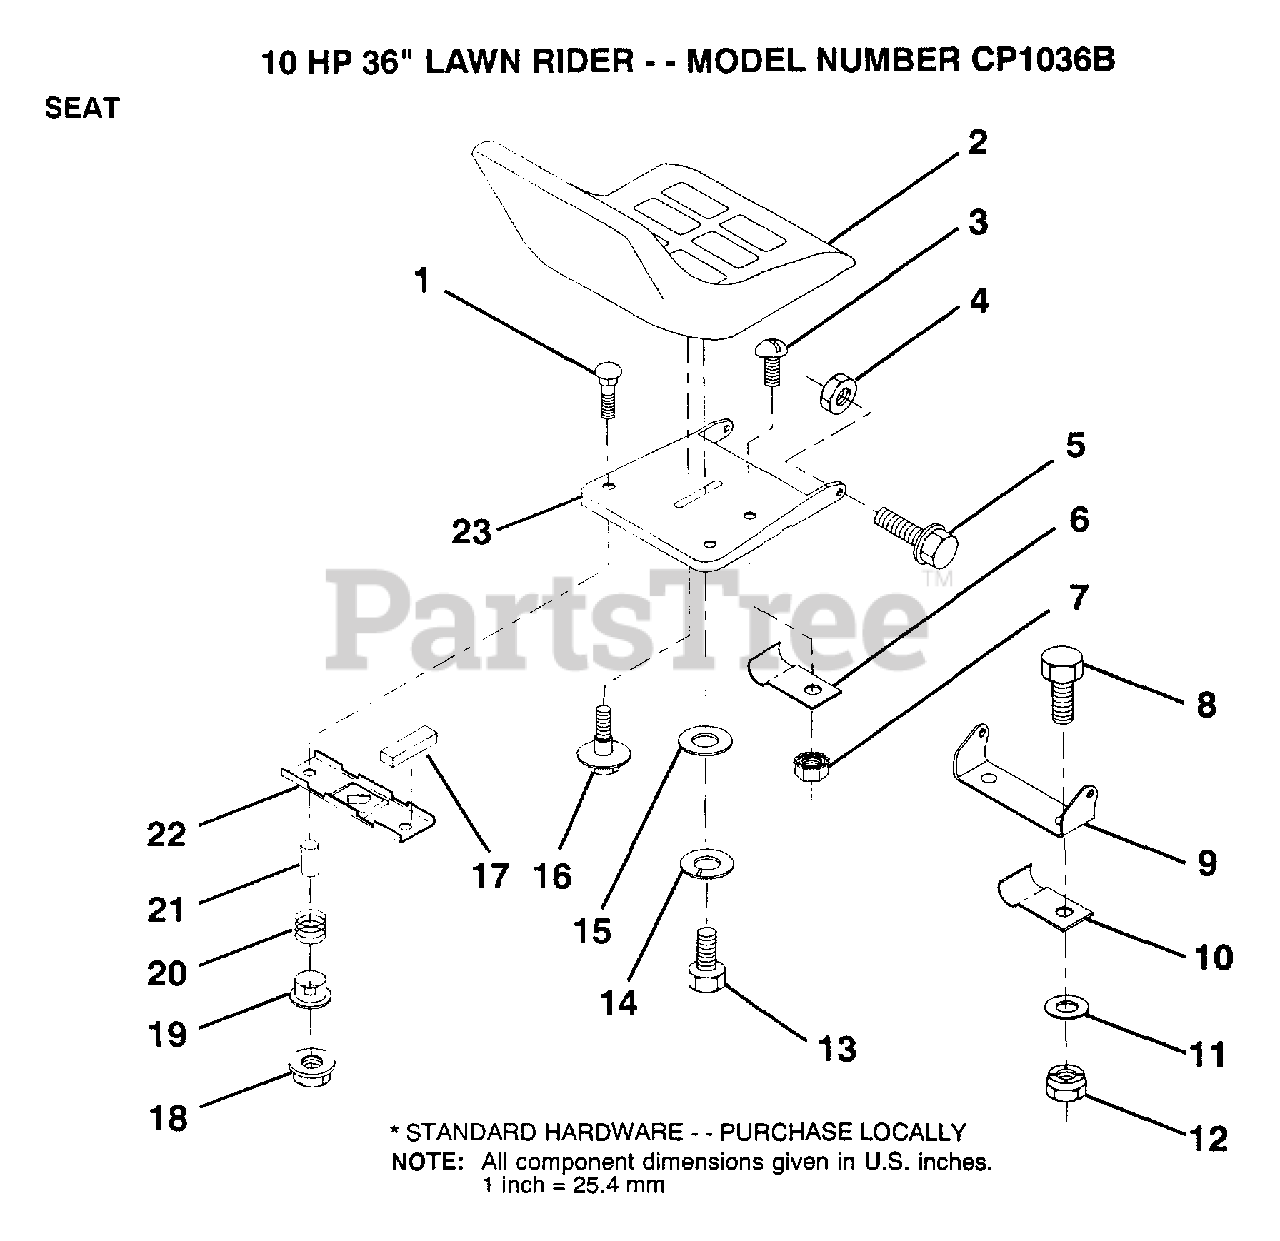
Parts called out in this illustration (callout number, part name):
7	"NUT,KEPS"
10	"CLIP,INSULATOR"
11	WASHER
13	BOLT
14	LOCKWASHER
15	WASHER
16	"BOLT,SHOULDER"
17	STRIP FORM
19	BUSHING
20	SPRING
21	SPACER SPLIT
22	BRKT SWITCH
